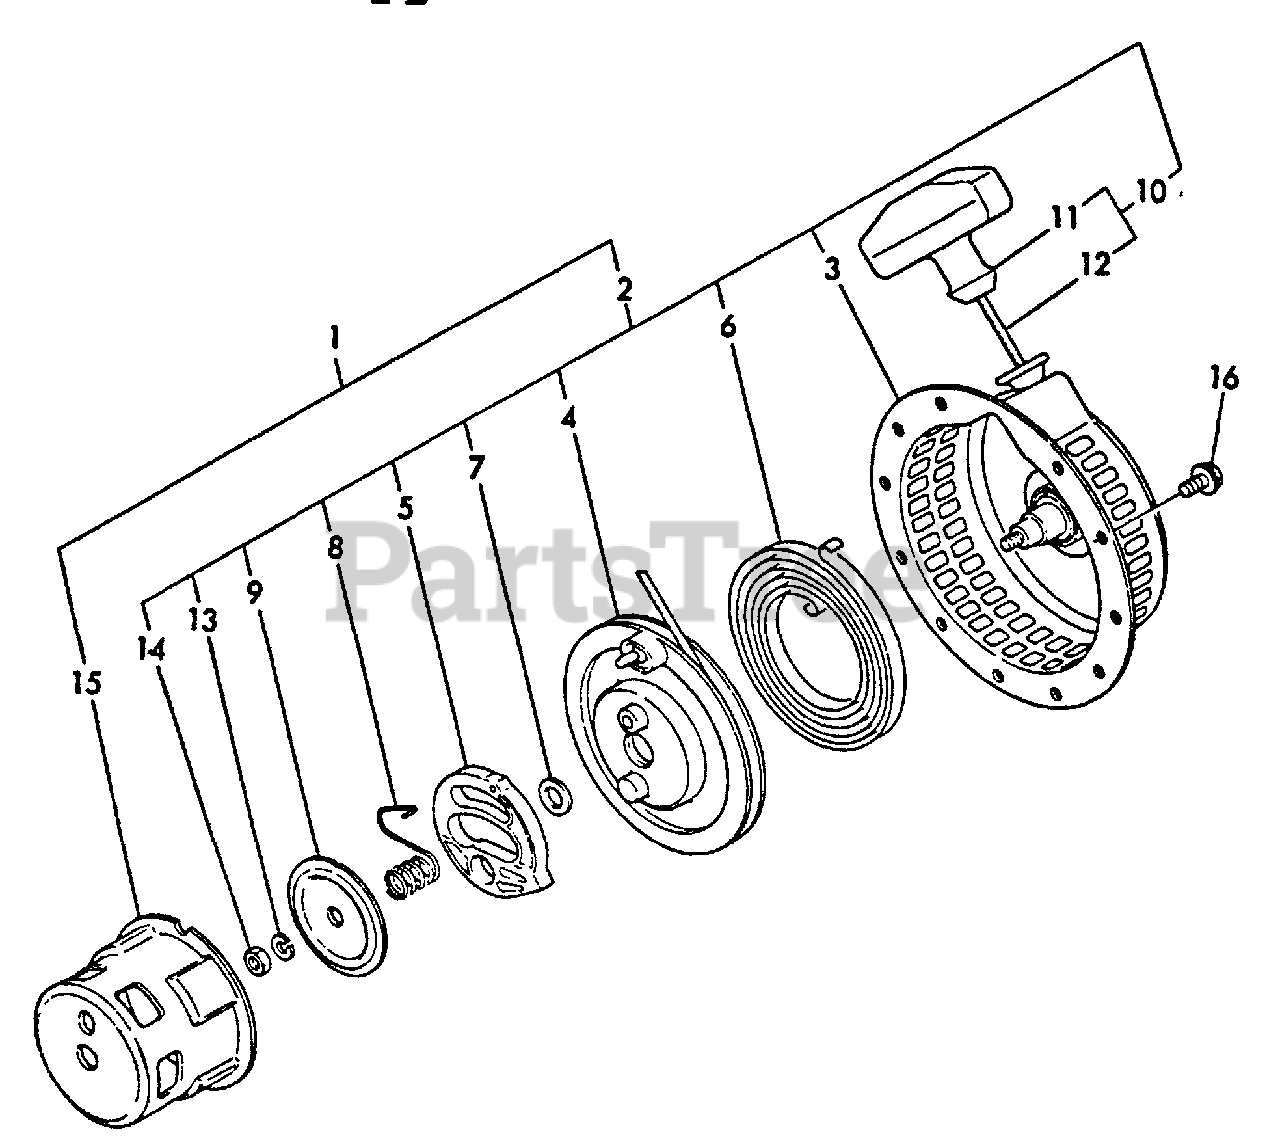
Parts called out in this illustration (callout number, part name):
1	STARTER ASSY, RECOIL
2	STARTER ASSY, RECOIL
3	CASE, STARTER
4	REEL
6	SPRING, SPIRAL
7	WASHER
8	SPRING
9	PLATE, FRICTION
10	STARTER ROPE ASSY
11	GRIP, STARTER
12	ROPE, STARTER
13	LOCKWASHER - 6
14	NUT - 6
15	PULLEY, STARTER
16	BOLT - 6×12 -- PLATED
